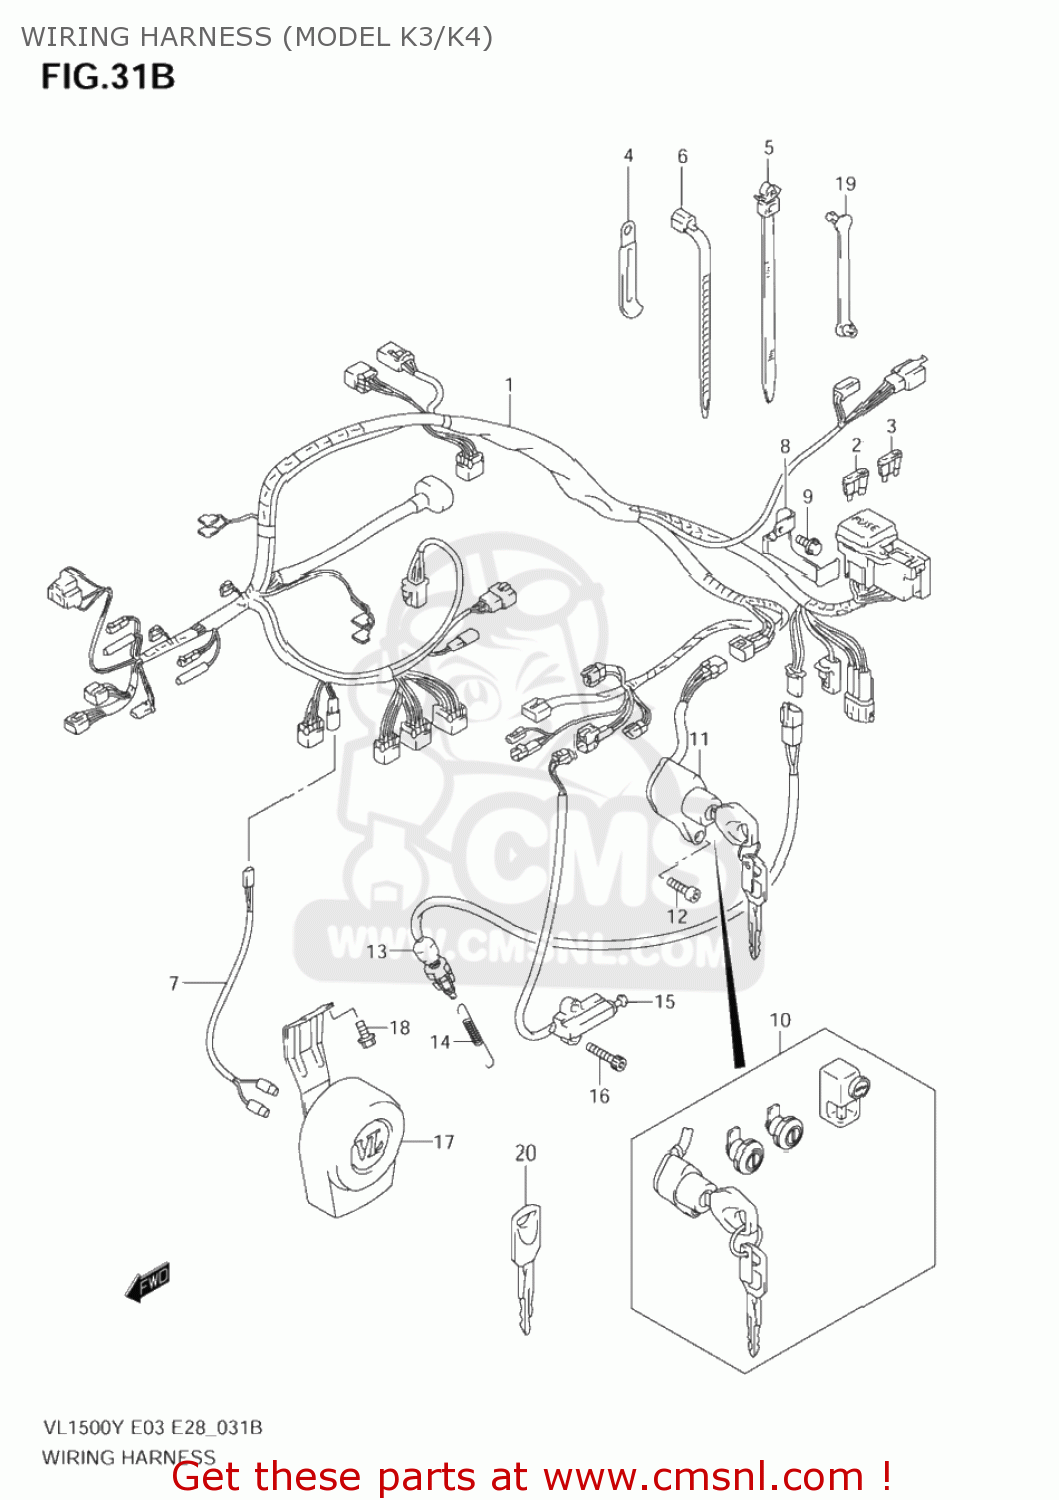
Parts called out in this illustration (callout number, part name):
1	HARNESS,WIRING
2	FUSE(10A)
3	FUSE(15A)
4	CLAMP(L:80)
5	CLAMP(L:90)
6	CLAMP(L:125)
7	WIRE,HORN LEAD
8	BRACKET,FUSE
9	BOLT
10	LOCK SET
11	SWITCH ASSY,IG
12	BOLT,OIL FILLE
13	SWITCH ASSY,STOP LAMP
14	SPRING,STOP LAMP SWITCH
15	SWITCH ASSY,SIDE STAND
16	SCREW
17	HORN ASSY
18	BOLT
19	CLAMP(L:33)
20	KEY,BLANK
